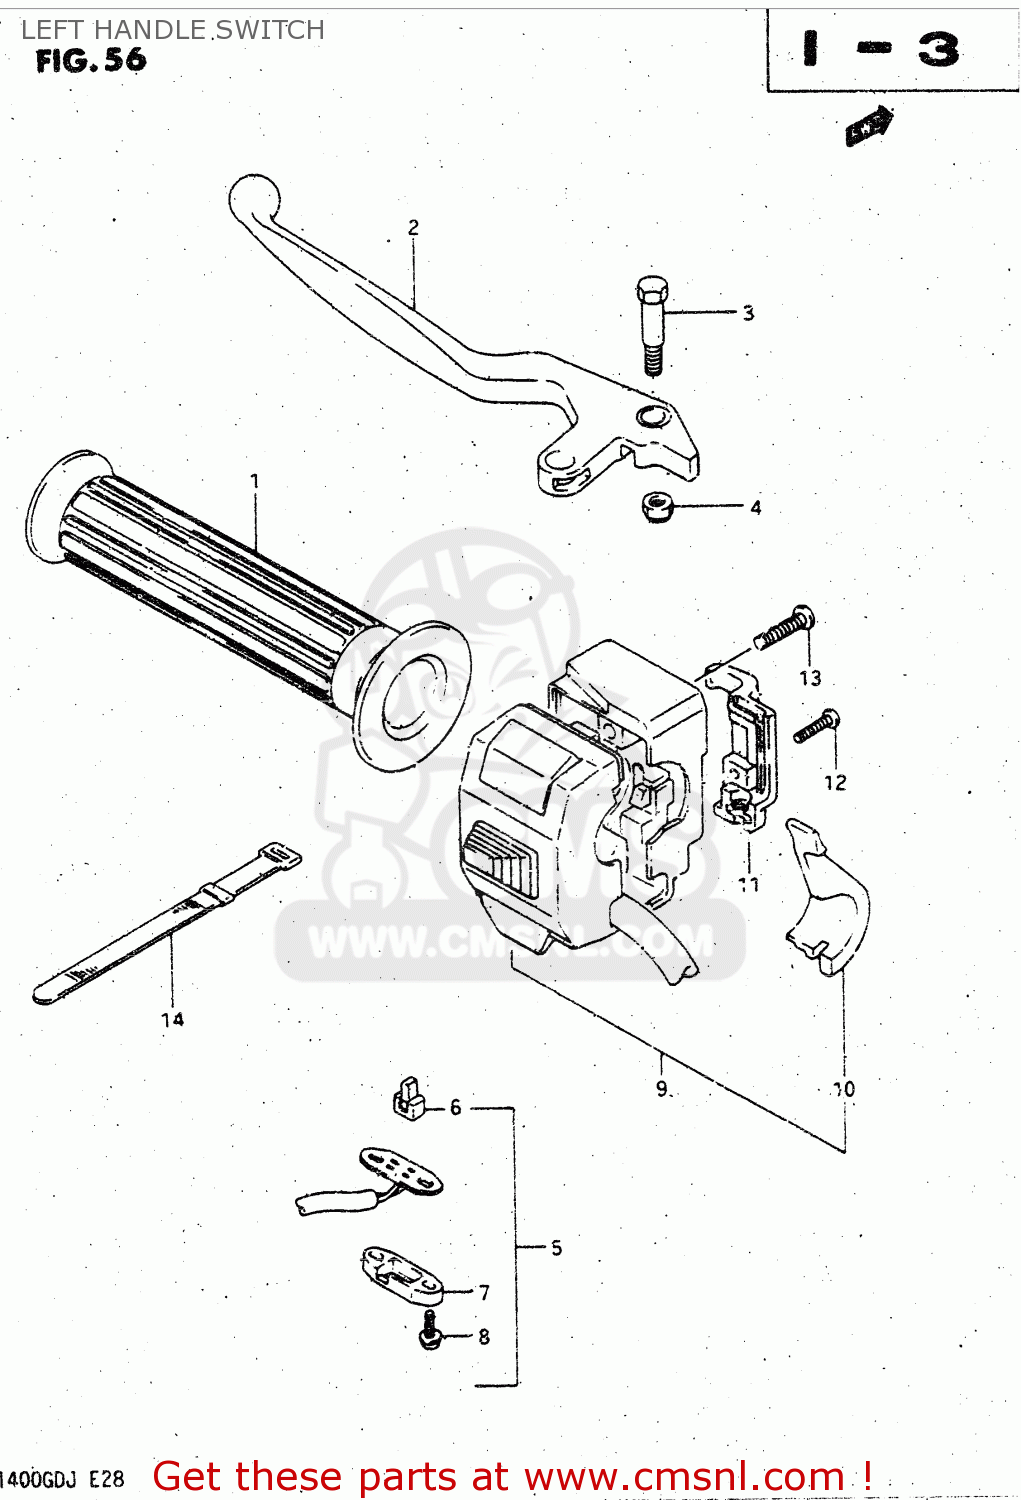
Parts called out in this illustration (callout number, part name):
1	GRIP,LEFT
2	LEVER,CLUTCH
3	BOLT,LEVER
4	NUT
5	SWITCH ASSY,CLUTCH
6	CONTACT,SWITCH
7	COVER,FR BK TERMINAL BASE
8	SCREW
9	SWITCH ASSY,HANDLE LH
10	LEVER,CHOKE
11	COVER
12	SCREW
13	SCREW 5X20
14	CLAMP(L:187)
